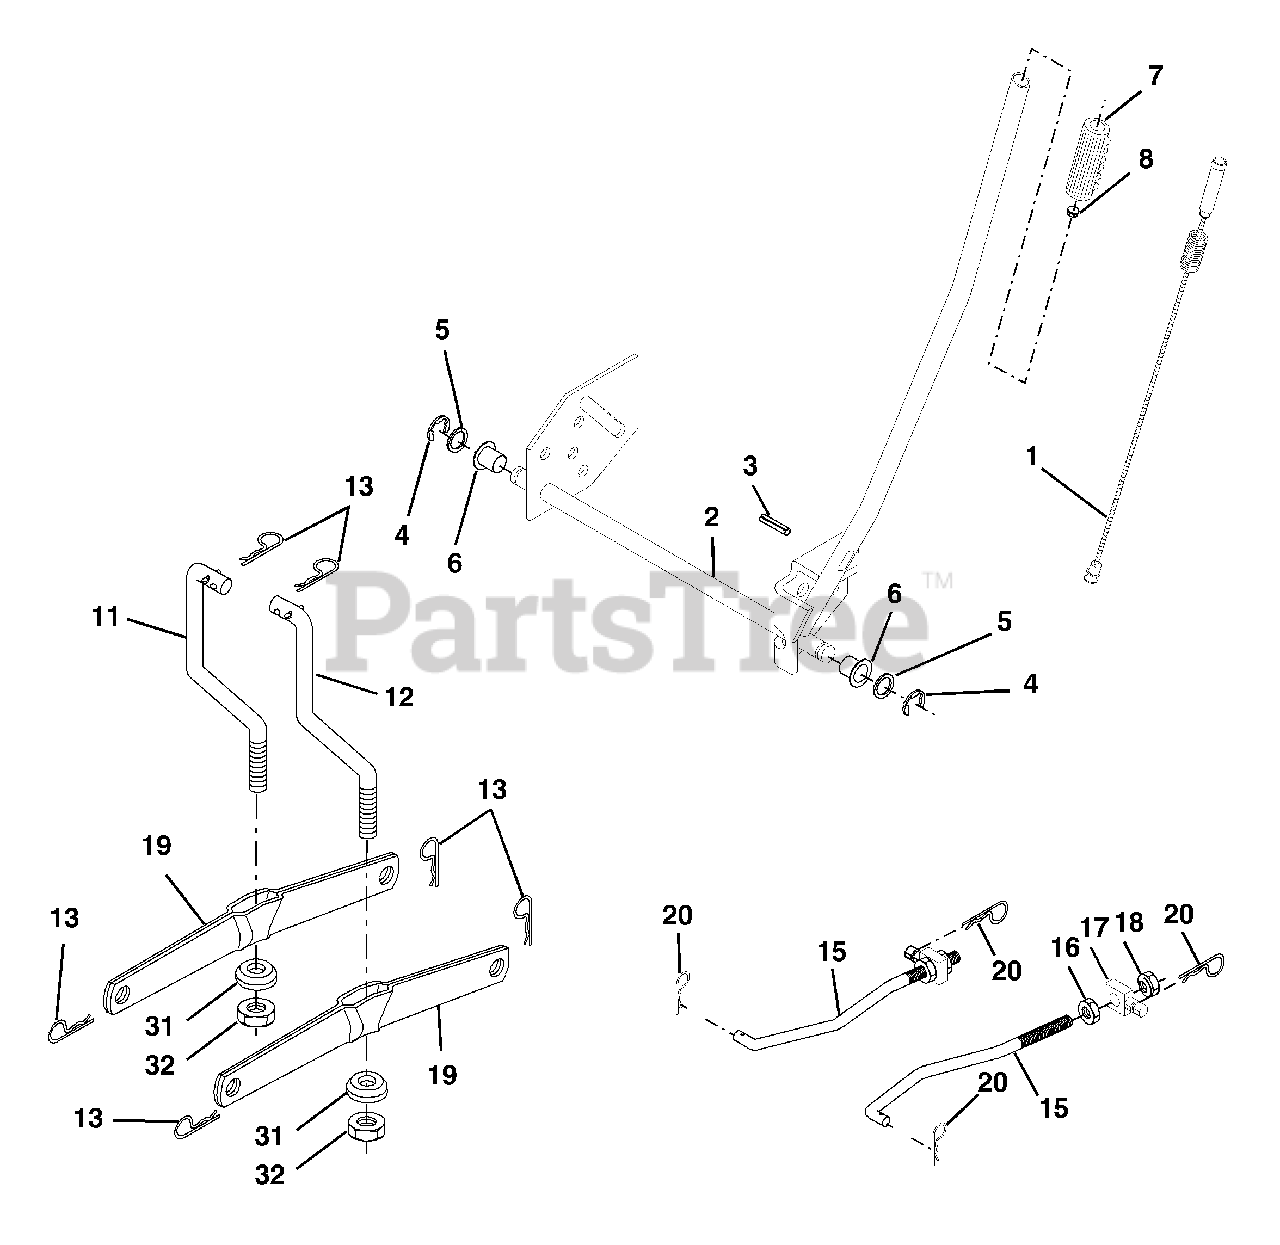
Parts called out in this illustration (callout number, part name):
1	Wire Asm Inner W/plunger LT
2	Shaft Asm Lift
3	Pin Groove
4	E Ring #5133-62
5	Washer PLTD 21/32 x 1 x 21 Ga.
6	Bearing Nylon Blk 629 Id
7	Grip Handle Bicycle
8	Button Plunger Black
11	Link Lift LH
12	Link Lift RH
13	Retainer Spring
15	Link Front
16	Nut Jam Hex 1/2-13 Unc
18	Nut Lock W/Wsh 1/2-13 Unc
19	Arm Suspension Rear
20	Spring, Retainer
31	Bearing Pvt. Lift
32	Nut Crownlock 3/8-24
